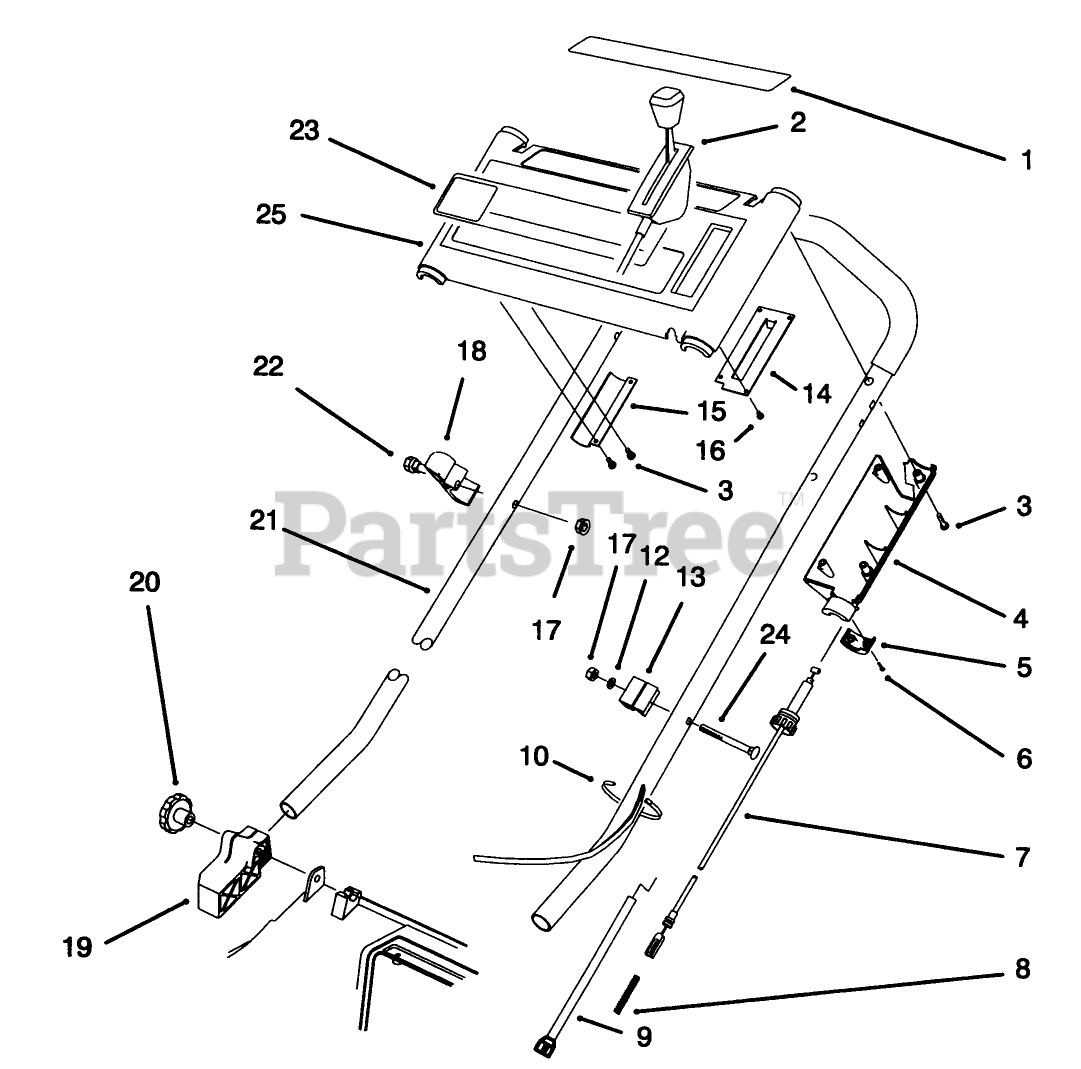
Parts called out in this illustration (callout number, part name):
2	CONTROL - THROTTLE
3	SCREW-PPH, PLASTITE
4	COVER-THROTTLE, LEVER
5	LOWER THROTTLE CAP
7	CABLE - TRACTION
8	SPRING-COMPRESSION
9	CABLE - BRAKE
10	TIE-CABLE
12	WASHER-FLAT
13	SUPPORT-CABLE
16	#6-19X.25 PLASK FORM SC
17	NUT-LOCK, NI
18	GUIDE - ROPE
19	MOUNT-HANDLE, RH
21	HANDLE (DIPPED)
23	DECAL - PANEL
24	SCREW-HANDLE
